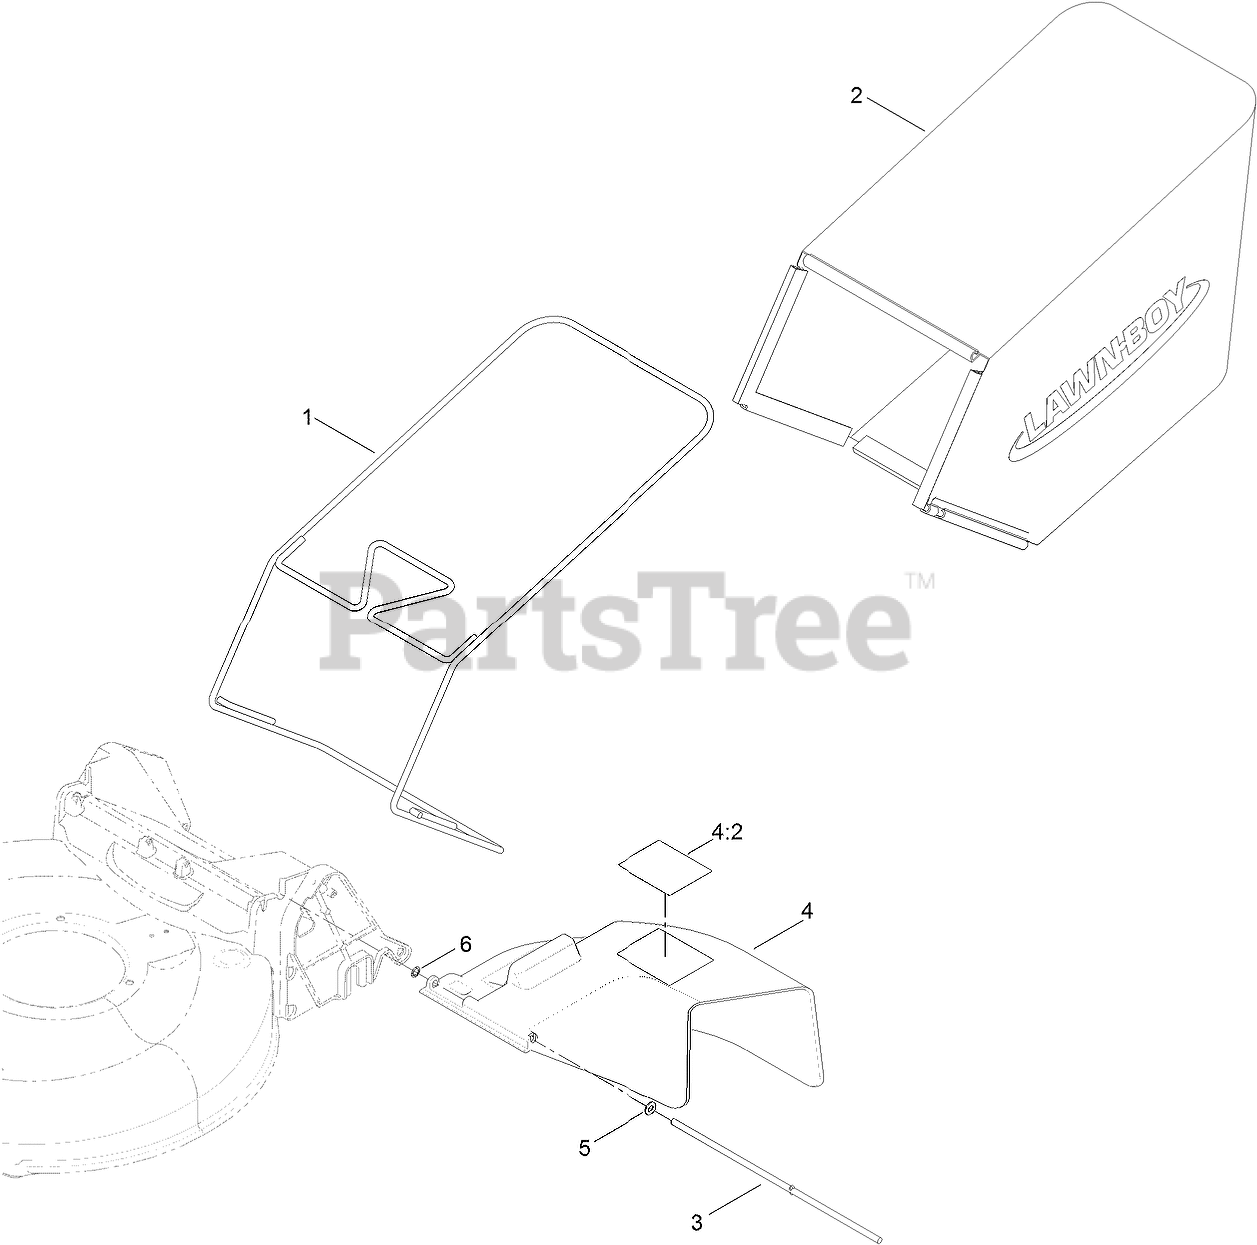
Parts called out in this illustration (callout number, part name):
1	FRAME-BAG
2	BAG-GRASS
3	ROD
4	DEFLECTOR-CHUTE
4:2	DECAL-WARNING
5	WASHER-PLAIN
6	RING-RETAINING
